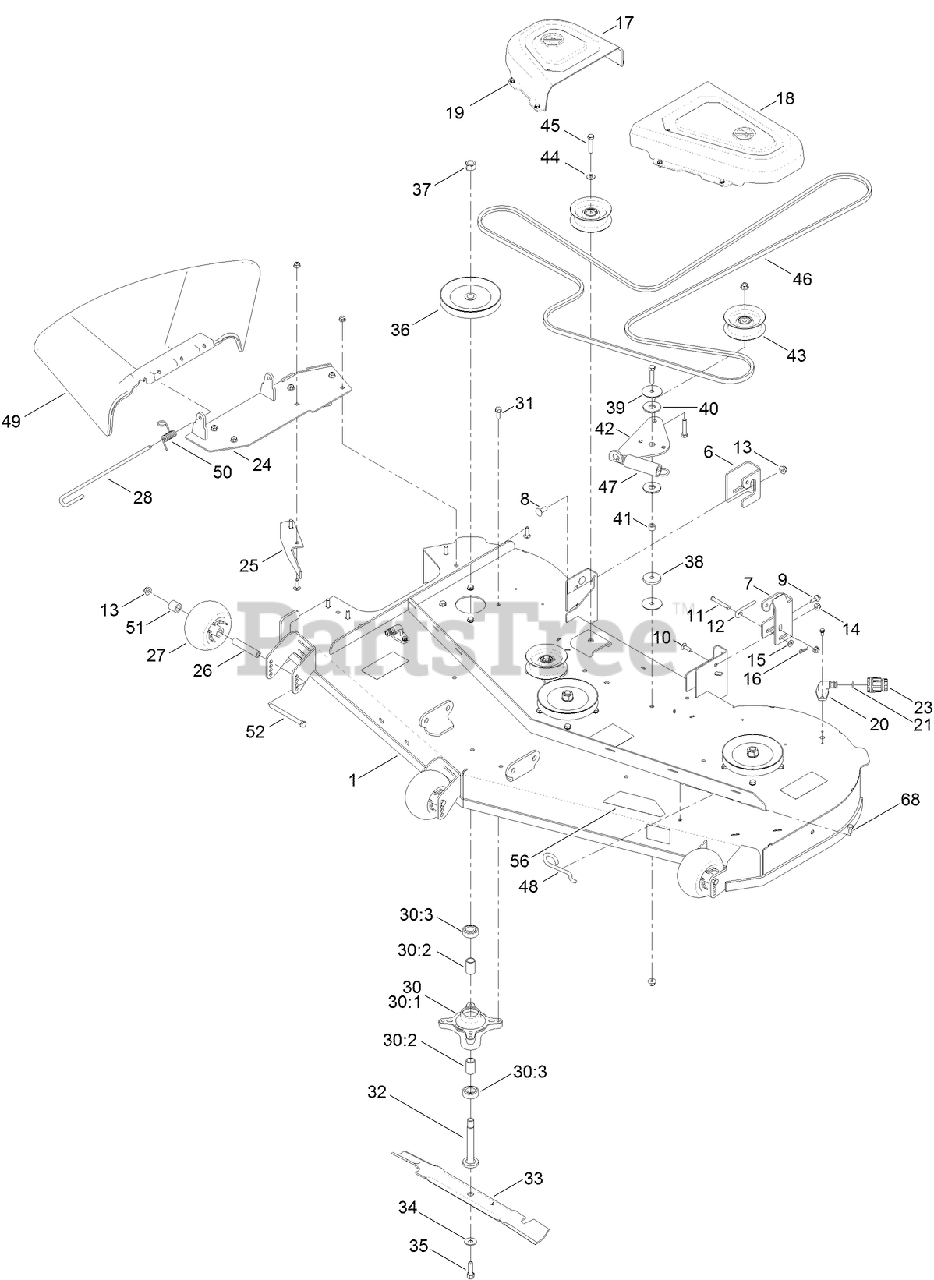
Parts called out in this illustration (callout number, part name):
1	60 INCH DECK AND DECAL ASM
6	BRACKET-HANGER, RH
7	BRACKET-HANGER, LH
8	BOLT-CARR
9	SCREW-SHOULDER,HWH
10	SCREW-CARR
11	PIN-CLEVIS
12	ROD-LEVEL, DECK
13	NUT-HF, NI
14	NUT-HF, NI
15	WASHER-PLAIN
16	PIN-COTTER
17	COVER-BELT, RH
18	COVER-BELT, LH
19	SCREW-HWH
21	O-RING
23	CONNECTOR-HOSE
24	PIVOT-DEFLECTOR
25	BAFFLE-CUTOFF
26	TUBE-SPANNER
27	ROLLER-SCALP, ANTI
28	PIN-CHUTE
30	SPINDLE ASM
30:2	SPACER
30:3	BEARING-BALL
31	SCREW-TAPTITE
32	SHAFT-SPINDLE
33	BLADE-HI FLOW, 20.5 INCH
34	WASHER-BELLEVILLE
35	SCREW-HH
36	PULLEY
37	NUT-HEX
38	WASHER-PLAIN
39	WASHER
40	WASHER-FRICTION, COMPOSITE
41	SPACER
42	ARM-IDLER
43	PULLEY-IDLER, FLAT
44	WASHER-FLAT
45	SCREW-HH
46	BELT
47	SPRING-EXTENSION
48	HOOK-RETURN, SPRING
49	DEFLECTOR-DISCHARGE
50	SPRING-TORSION
51	SPACER-AXLE, REAR
52	SCREW-HH
68	SCREW-HH
